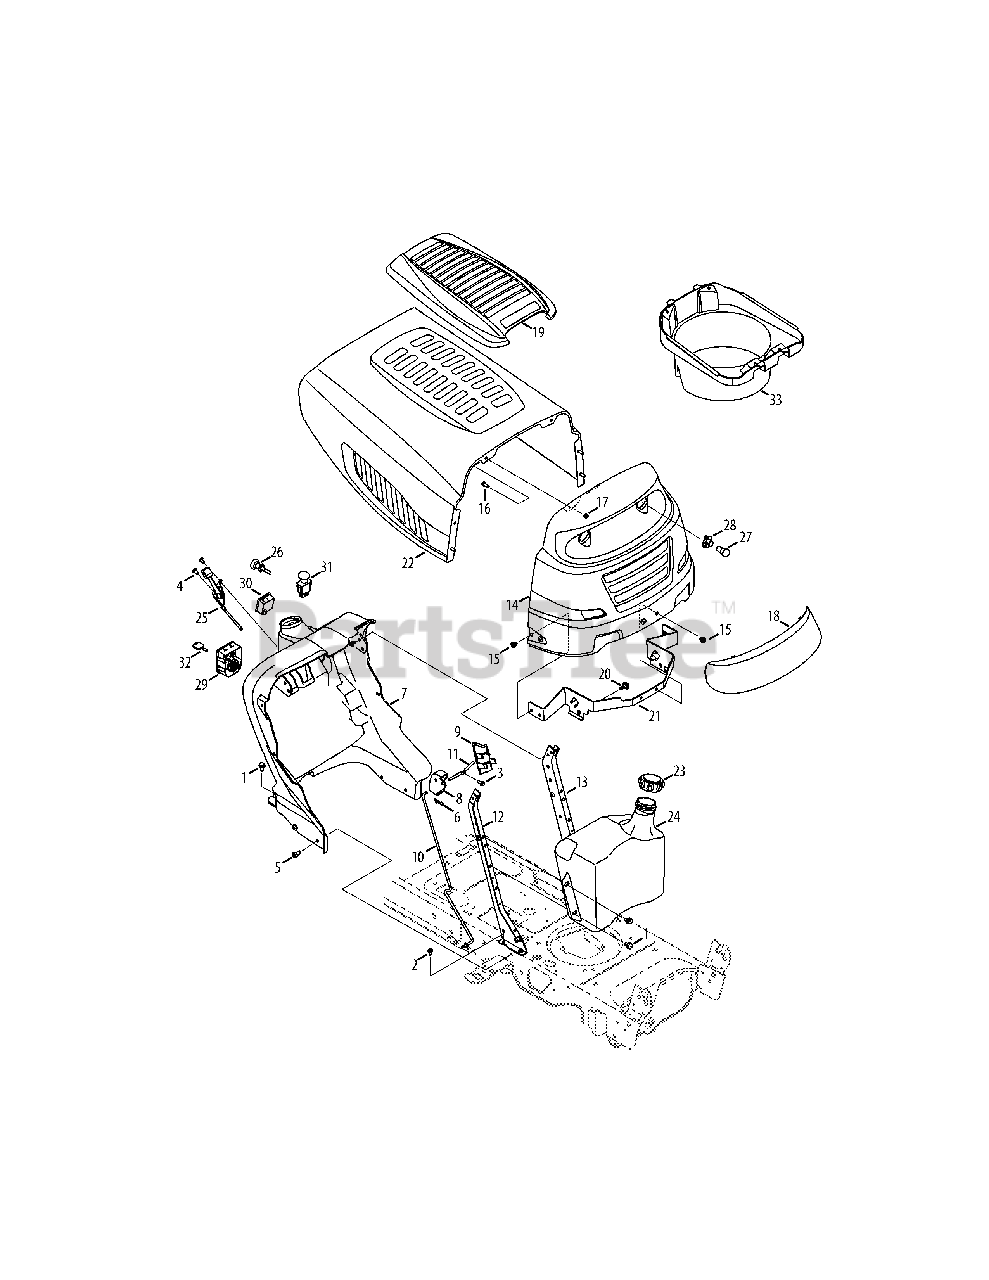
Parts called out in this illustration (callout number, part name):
1	Taptite Screw ,5/16-18x.750
2	Taptite Screw ,1/4-20x0.500
3	Hi-Lo Screw, 1/4-15x0.750
4	Screw, 1/4-14x0.625
5	Taptite Screw ,5/16-18x0.750
6	Bow Tie Cotter Pin
7	Dash Panel
8	Dash Lever
9	Cruise Cover
10	Control Rod
11	Lever
12	RH Support Plate
13	LH Support Plate
14	Grill
15	Taptite Screw ,5/16-18x0.375
16	Hex Screw, 1/4-20x.620
17	Flangelock Nut, 1/4-20
18	Grill Lens
19	Hood Scoop
20	Shoulder Screw, .43X.29 5/16-18
21	Hood Pivot Bracket
23	Fuel Cap 3 Gal
23	Fuel Cap w/Hoop Vented 2.5 Gal
24	Fuel Tank 3 Gallon
24	Fuel Tank 2.5 Gallon
25	Throttle Control
26	Choke Control
28	Lamp Socket
29	Key Switch
30	Hour Meter
31	Electric PTO Switch
